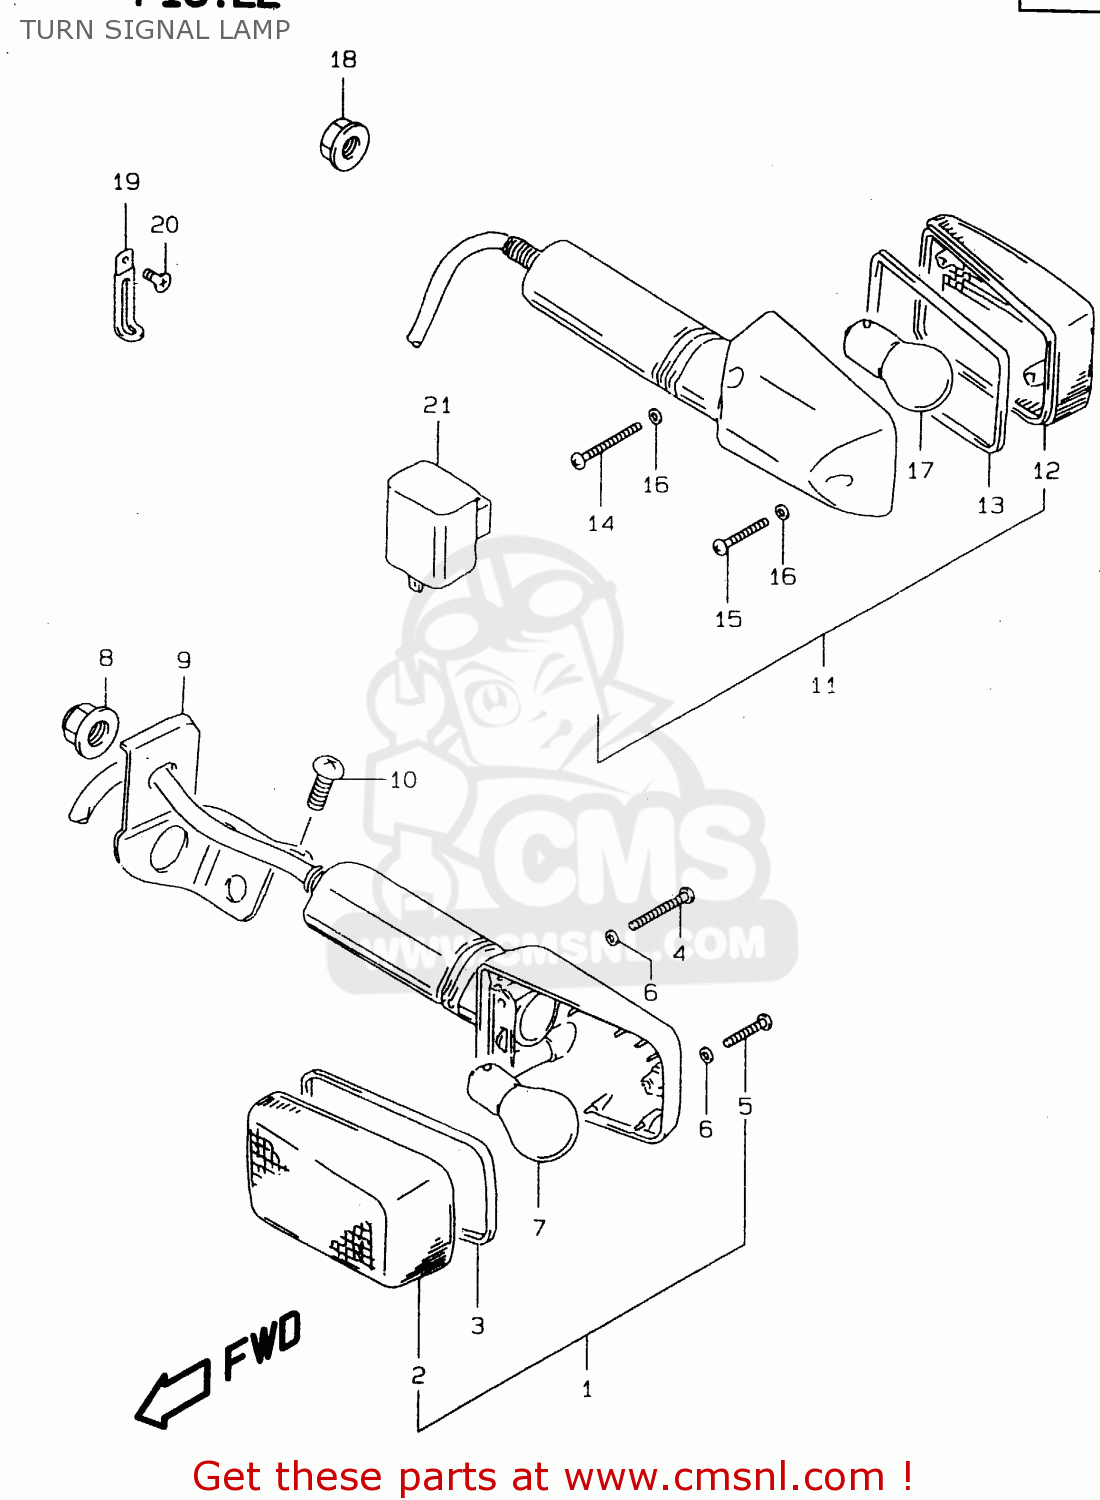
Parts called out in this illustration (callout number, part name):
1	LAMP ASSY,FR TURN SIGNAL
2	LENS
3	GASKET (NAS)
4	SCREW(3X30)
5	SCREW
6	GASKET (NAS)
7	BULB(12V21W)
8	NUT
9	BRACKET,FR TURN,R
10	SCREW
11	LAMP ASSY,RR TURNSIGNAL,R
12	LENS
13	GASKET (NAS)
14	SCREW(3X30)
15	SCREW
16	GASKET (NAS)
17	BULB(12V21W)
18	NUT
19	CLAMP(L:65)
20	SCREW
21	RELAY ASSY,TURNSIGNAL
